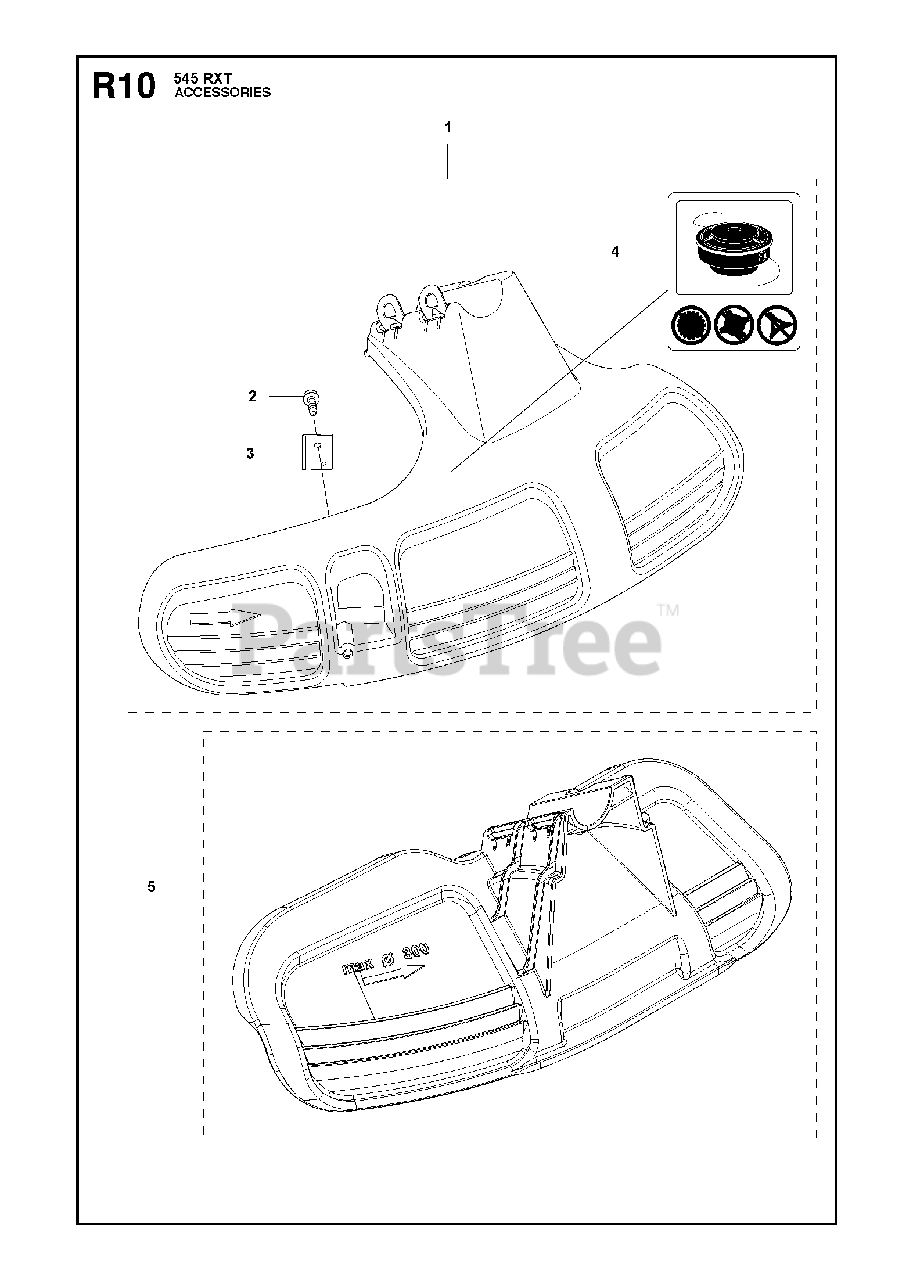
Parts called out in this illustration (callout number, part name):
1	BLADE GUARD
2	SCREW
3	LINE CUTTER
4	DECAL
5	BLADE GUARD
